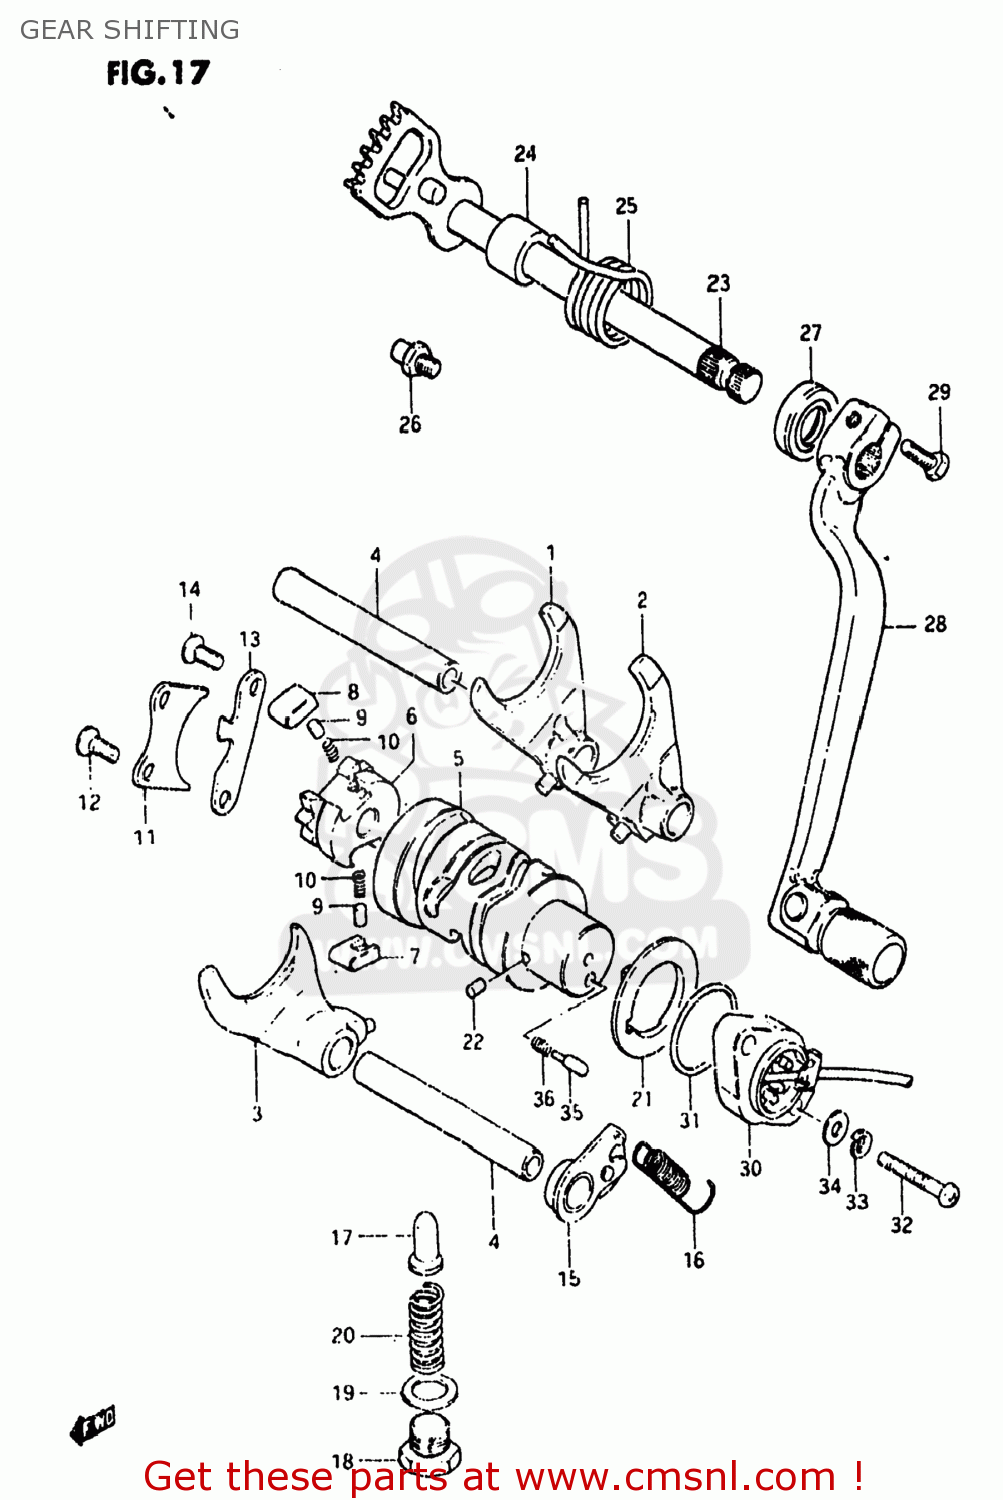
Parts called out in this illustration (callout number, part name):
1	FORK,GEAR SHIFT NO.1
2	FORK,GEAR SHIFT
3	FORK,GEAR SHIFT NO.3
4	SHAFT,GEAR SHIFT FORK
5	CAM,GEAR SHIFT
6	RETAINER,GEAR SHIFT CAM
7	PAWL,GEAR SHIFT NO.1
8	PAWL,GEAR SHIFT NO.2
9	PIN(5X8)
10	SPRING
11	LIFTER,GEAR SHIFT PAWL
12	SCREW
13	GUIDE,GEAR SHIFT CAM
14	SCREW
15	STOPPER,GEAR SHIFT CAM
16	SPRING
17	STOPPER,GEAR SHIFT CAM NO.2
18	PLUG (14X12)
19	GASKET(14X19.2X2) (NAS)
20	SPRING
21	PLATE,GEAR SHIFT CAM STOPPER
22	PIN 4X6
23	SHAFT,GEAR SHIFT
24	SPACER(12X20X15.3)
25	SPRING
26	STOPPER,GEAR SHIFT CAM
27	OIL SEAL
28	LEVER ASSY,GEAR SHIFT
29	BOLT
30	TERMINAL BASE,NEUTRAL SWITCH
31	O-RING (D:2.4 ID:26.2)
32	SCREW 5X20
33	LOCK WASHER
34	WASHER
35	PIN(5X15.5)
36	SPRING
